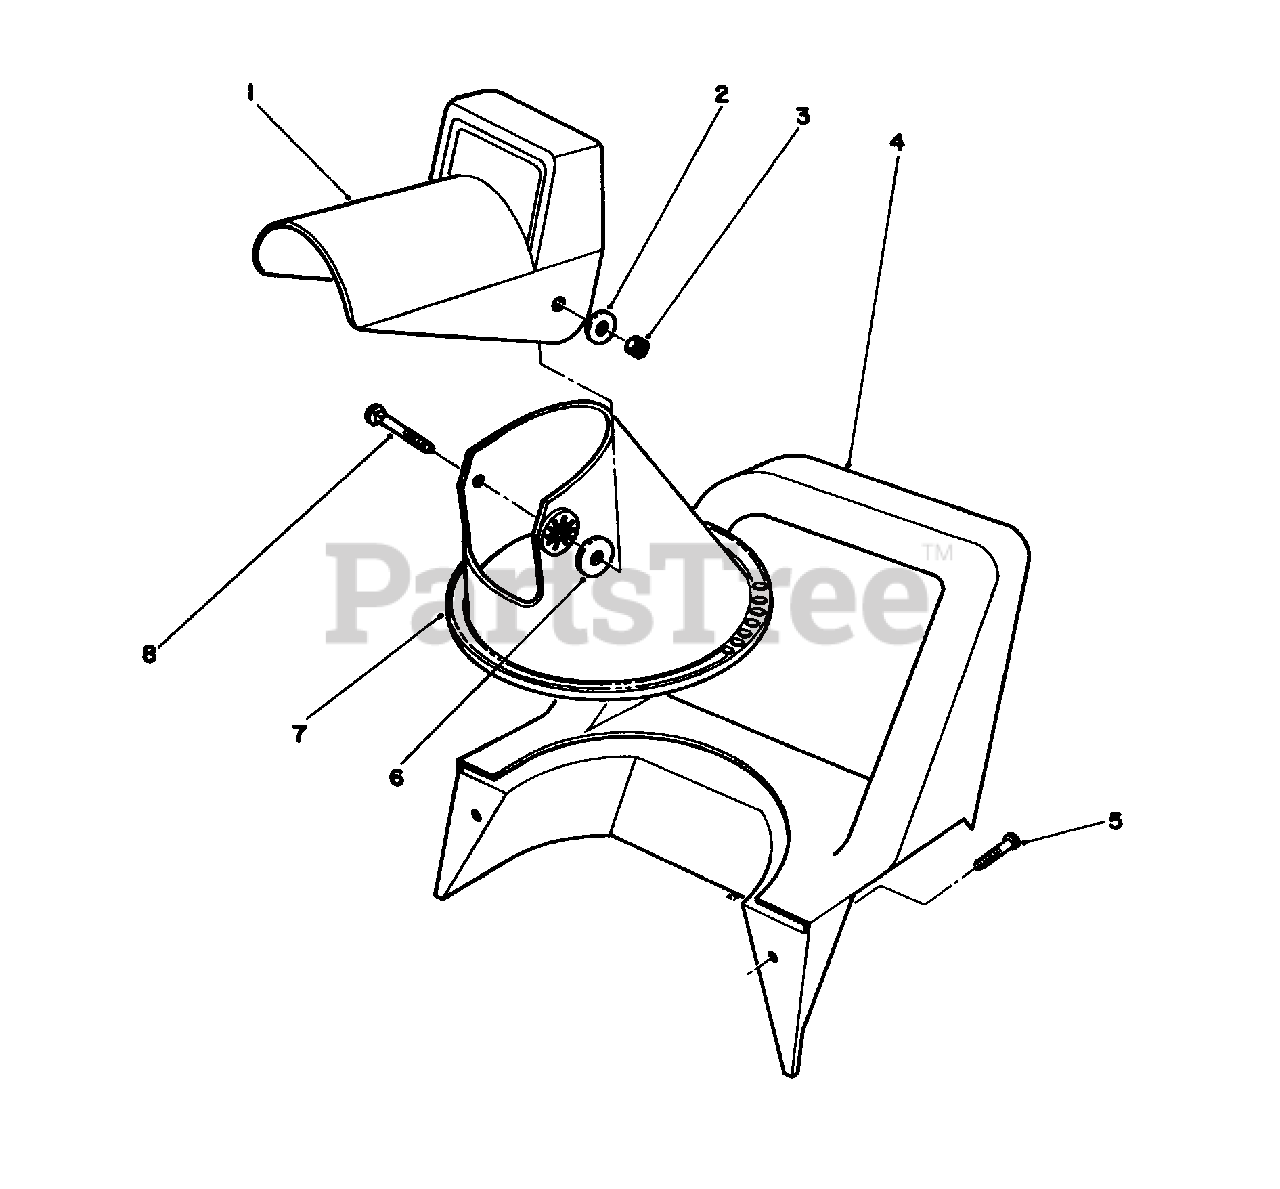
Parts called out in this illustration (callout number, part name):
1	Chute-Deflector
2	Washer-Flat
3	Nut-Lock
4	Handle-Middle
5	Screw-Pan Hd. Form.
6	Washer-Rubber
7	Chute-Lower
8	Bolt-Carriage
